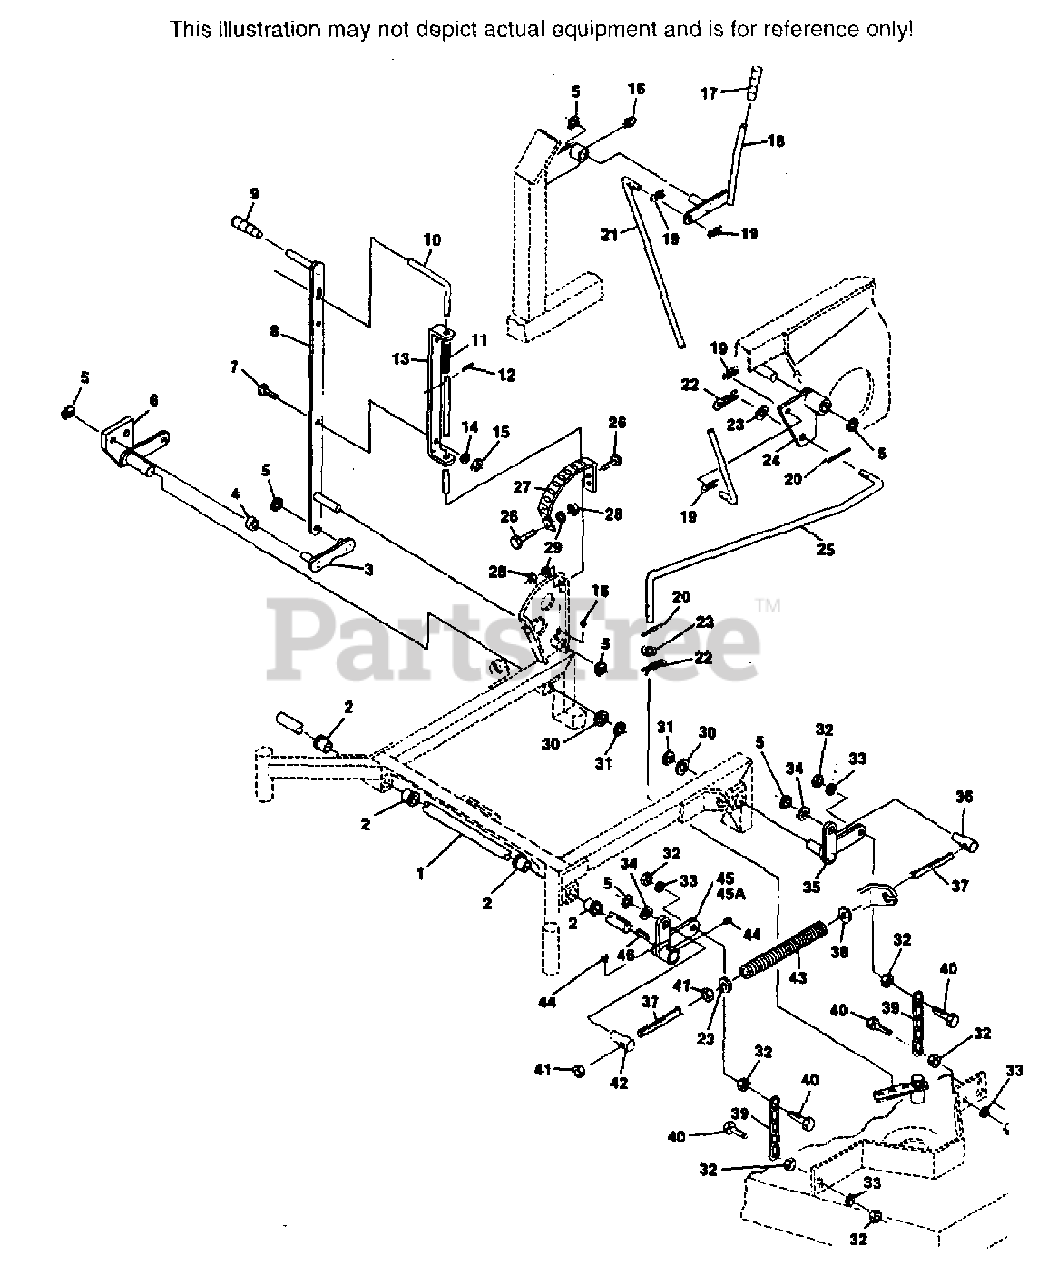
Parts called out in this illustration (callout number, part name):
1	SHAFT, CUTTER DECK
2	BUSHING
3	LIFT LINK
4	BUSHING
5	RETAINING RING, 5/8" EXTERNAL "E"
6	BELLCRANK, LIFT - RIGHT REAR
8	HEIGHT ADJUSTMENT LEVER(INCLUDES GRIP)
9	GRIP, LIFT LEVER
10	ROD, CUTTER DECK LOCK
11	SPRING, DECK LIFT INDEX
12	ROLL PIN, 5/32 X 3/4
13	LOCK ROD GUIDE
16	GREASE FITTING
17	GRIP, BLADE CLUTCH LEVER
18	LEVER, CUTTER ENGAGEMENT(INCLUDES GRIP)
19	HAIR PIN, 1/16" DIA.
20	COTTER PIN, 3/32 X 1
21	ROD, CUTTER ENGAGEMENT - UPPER
22	HAIR PIN, 1/8" DIA.
24	BELLCRANK, CUTTER ENGAGEMENT
25	ROD, CUTTER ENGAGEMENT - LOWER
27	STRIP, HEIGHT ADJUSTMENT
30	FLAT WASHER, 3/4 SPECIAL
31	RETAINING RING, 3/4" EXTERNAL "E"
35	BELLCRANK, LIFT - LEFT REAR
36	SWIVEL JOINT - RH
37	ADJUSTMENT STUD
38	FLAT WASHER, 5/8 ID
39	CHAIN
42	SWIVEL JOINT - LH
43	SPRING, DECK LIFT
44	SETSCREW, 5/16-18 X 1/4
45	BELLCRANK, LIFT - LEFT FRONT
45A	BELLCRANK, LIFT - RIGHT FRONT
46	KEY, 3/16 X 3/16 X 1"
